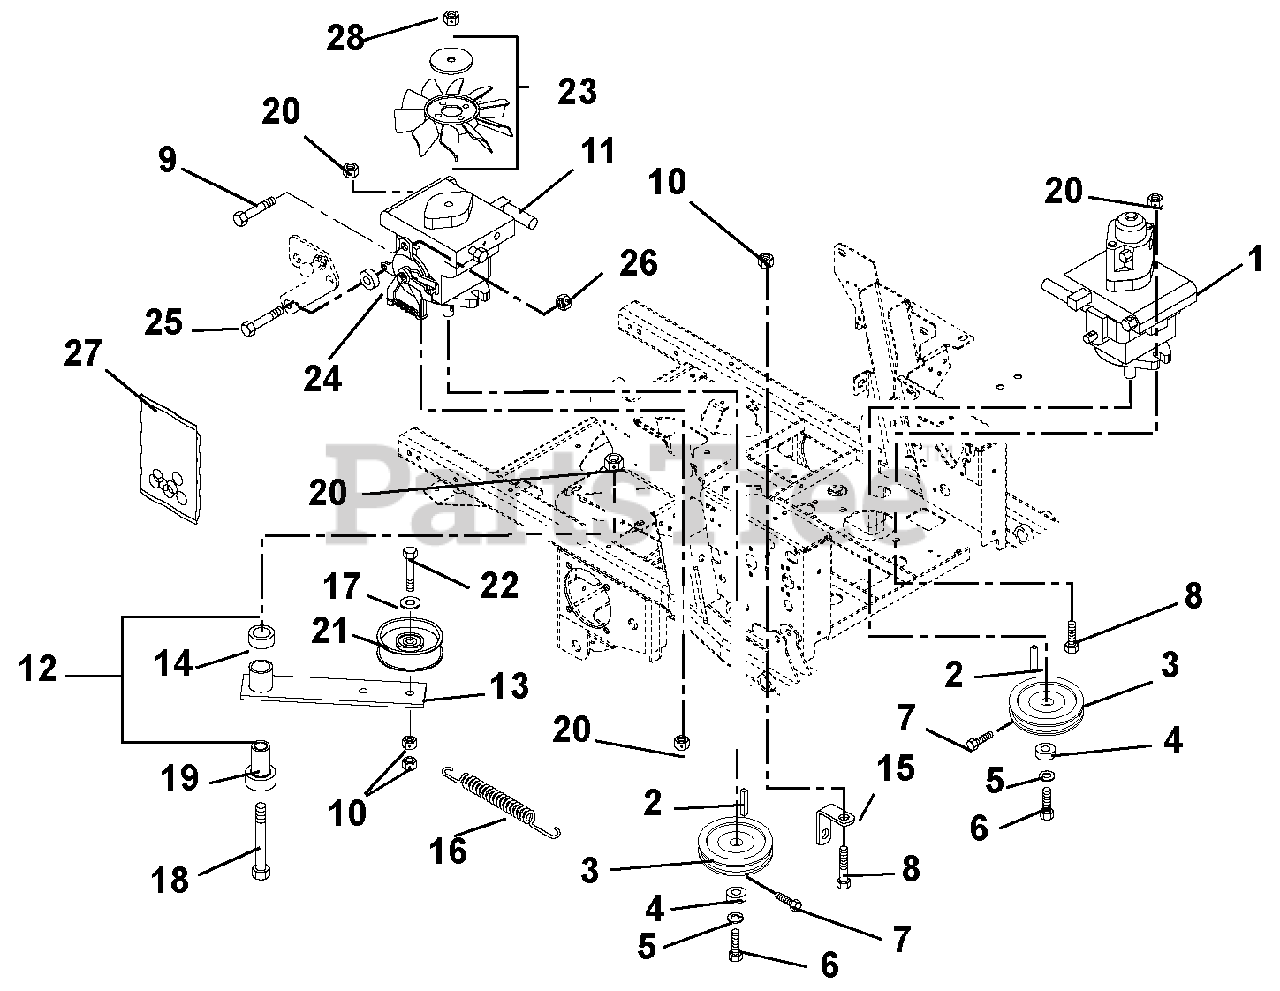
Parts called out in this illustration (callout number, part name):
1	Pump, Hydraulic with Auxiliary (992213, 217, 219) (page 17)
2	Key, Square 5 x 5 x 30mm Plain
3	Sheave, Poly V .671 x 4.125
4	Washer, Flat Steel .281 x 1.000 x .063
5	Washer, Locking .25 x .062
6	Bolt, Hex M6 x 1.0 x 12 YZ EP30
7	Screw, Socket Head .25-20 x .50 YZ EP80
8	Bolt, Hex .50-13 x 1.50 Grade 5
9	Bolt, Hex .31-18 x .75 Grade 5
10	Nut, Locking Top Flange .38-16
11	Pump, Hydraulic BDP – 21 with Thru Fan (page 19)
12	Assembly, Idler Arm Guard Drive (Includes 13 & 14)
13	Weldment, Idler Arm Ground Drive
14	Bushing, 1.00 x 1.125 x 1.936
15	Anchor, Spring Idler
16	Spring, Tension
17	Washer, Flat Steel .39 x .75 x.125
18	Bolt, Hex .50-13 x 3.50 Grade 5
19	Bearing, Pedestal
20	Nut, Locking Top Flange .50-13
21	Idler, Flat 4.00 x .38
22	Bolt, Hex .38-16 x 2.25 Grade 5
23	Fan, Cooling
24	Spacer .318 x .43 x .375
25	Bolt, Hex .31-18 x 1.25 Grade 5
26	Nut, Locking Top Flange .31-18
27	Kit, Pump Seal (BDP – 21A) (One kit required for each pump)
28	Nut, Center Lock .31-24
